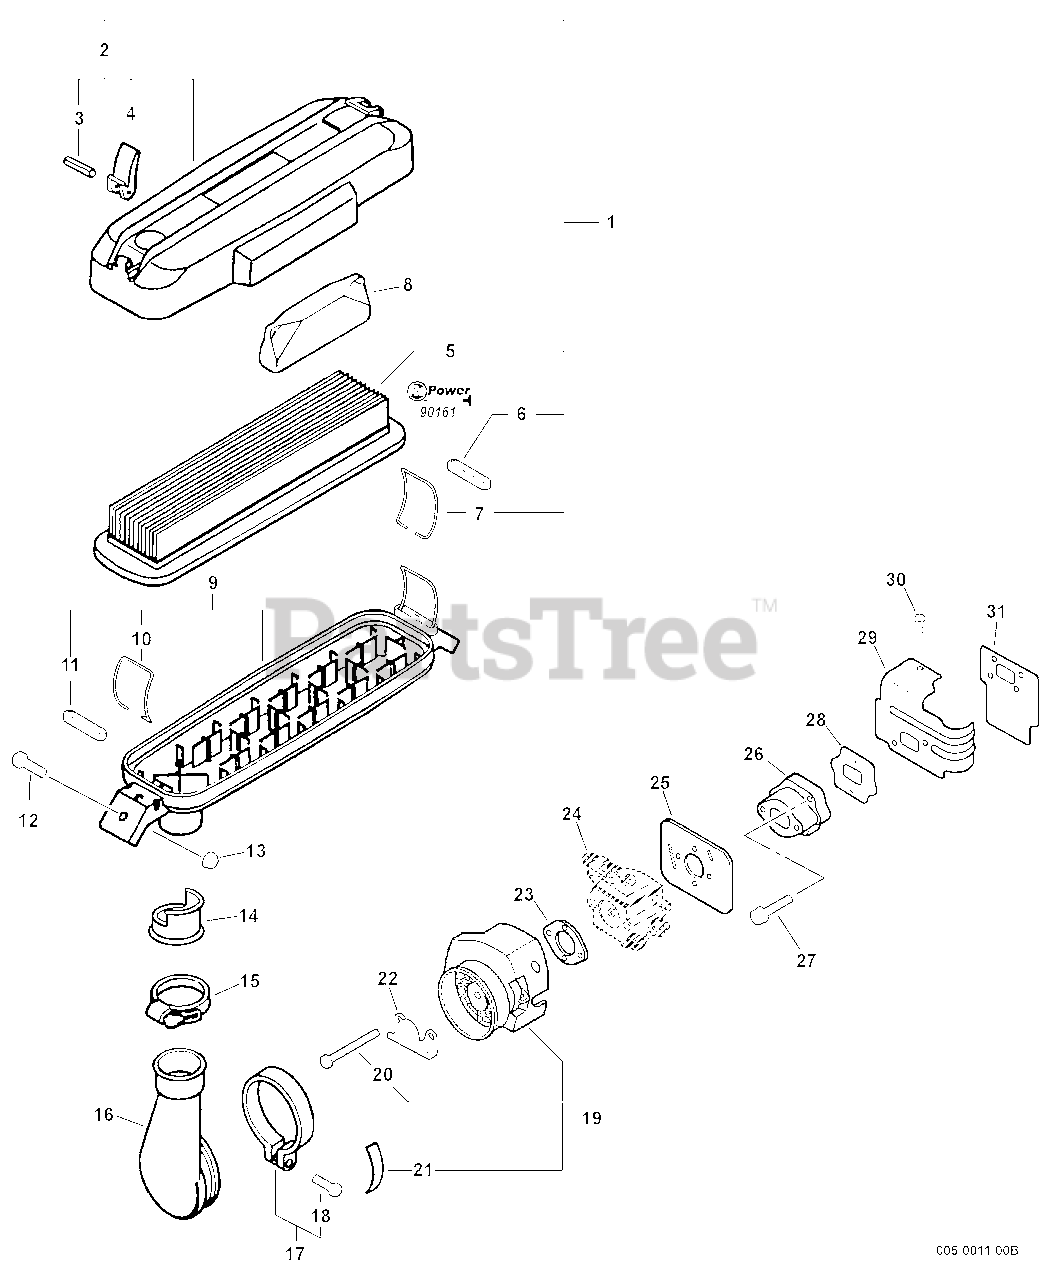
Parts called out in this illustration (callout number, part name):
1	AIR FILTER KIT
2	COVER ASSY, AIR FILTER
3	PIN, SPRING 3×25
5	FILTER, AIR
8	SILENCER
9	CASE ASSY, AIR FILTER
12	SCREW 5×14
13	NUT, FLANGE M5
14	COLLAR 27
16	ADAPTOR, INTAKE
17	CLAMP KIT
18	SCREW 5×25
19	BRACKET KIT, AIR FILTER
20	SCREW 5×57
21	LABEL, CHOKE
22	PLATE, PREVENT
23	GASKET, INTAKE
24	CARBURETOR
25	GASKET, INTAKE
26	INSULATOR, INTAKE
27	BOLT 5×25
28	GASKET, INTAKE
29	COVER, CYLINDER
30	SCREW 5×10
31	HEAT SHIELD, INTAKE
32	TUNE-UP KIT - REPOWER
